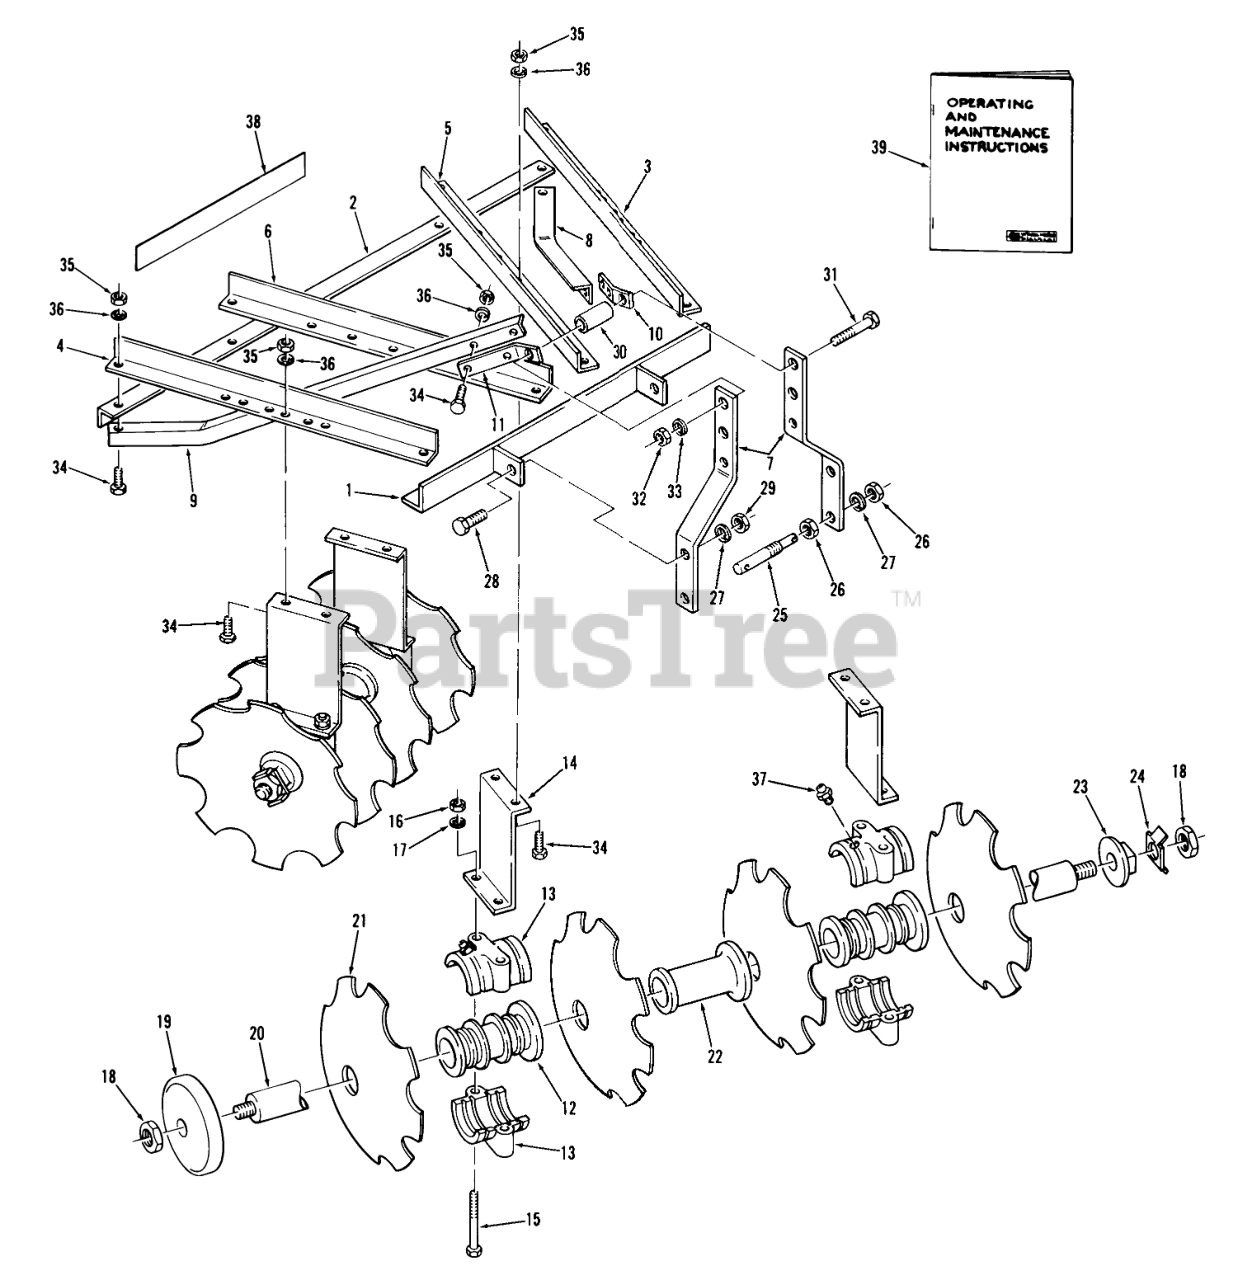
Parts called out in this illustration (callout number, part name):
1	Hitch Angle
2	Rear Main Frame
3	Outside-Left
4	Outside-Right
5	Inside-Left
6	Inside-Right
7	Rizer Strut
8	Strut Brace-Left
9	Strut Brace-Right
10	Strut Adapter-Left
11	Strut Adapter Right
12	Spool Bearing
13	Bearing Cap
14	Bearing Arm
15	Carriage Bolt 1/2-13 x 5
16	Nut 1/2-13
17	Lockwasher
18	Jam Nut 1-8
19	Bumper Washer
20	Gang Rod
21	Notched Blade-16 in. (40.6 cm)
22	Spacer Spool
23	End Washer
24	Lockwasher
25	Combination 5/8 & 7/8 Hitch Pin
26	Jam Nut 7/8-14
27	Lockwasher 7/8
28	Bolt 7/8-14 x 2 1/2
29	Nut 7/8-14
30	Top Link Spacer
31	Bolt 3/4-l0 X 4
32	Nut 3/4-10
33	Lockwasher 3/4
34	Hhcs
35	Nut 1/2-13
36	Lockwasher
37	Grease Fitting
38	DECAL-WHEEL HORSE
39	Operating and Maintenance Instructions
